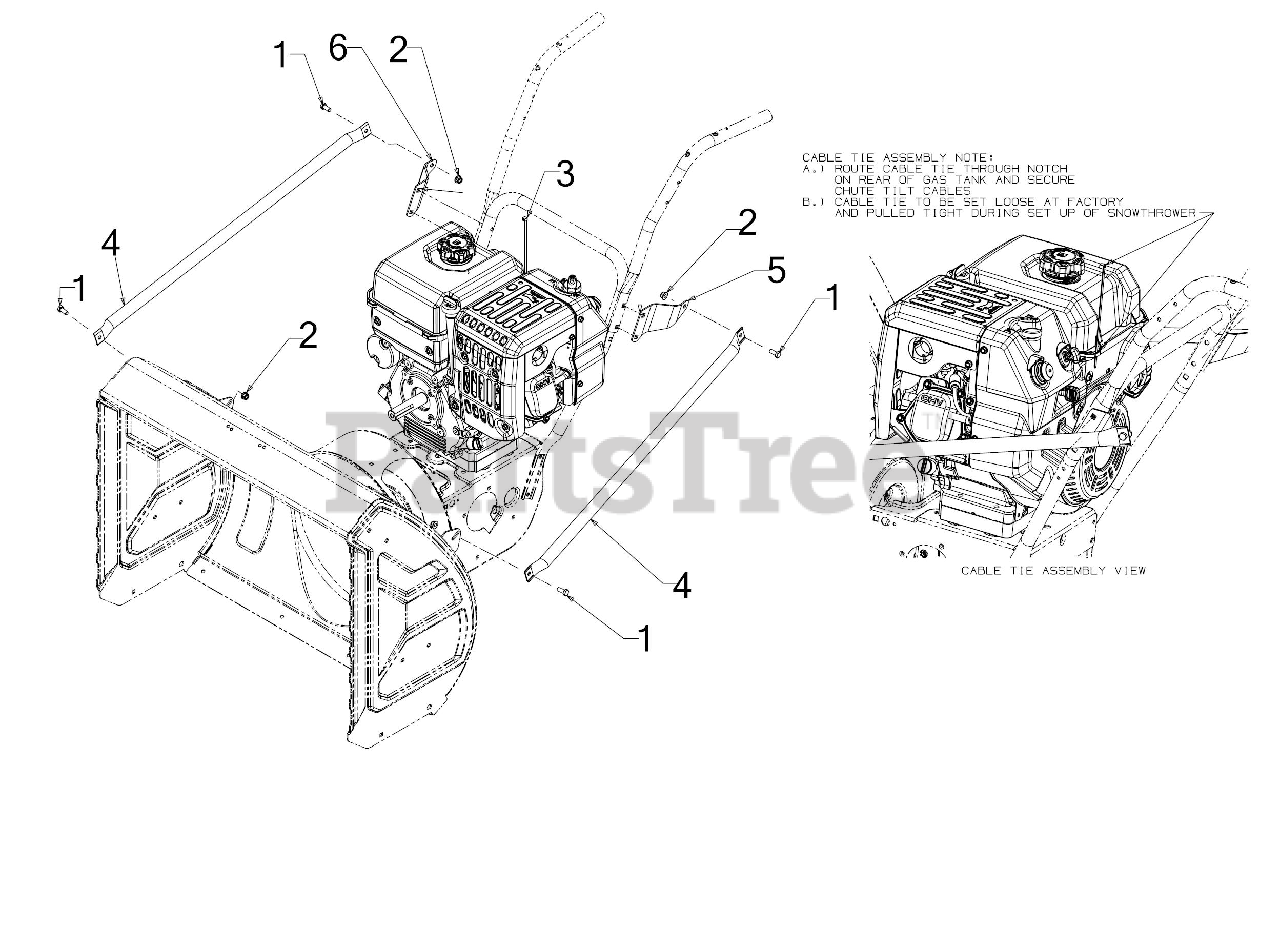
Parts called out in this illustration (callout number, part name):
1	SCREW 5/16-18 x .75 GR5
2	FLANGE LOCK NUT 5/16-18
3	7" CABLE TIE
